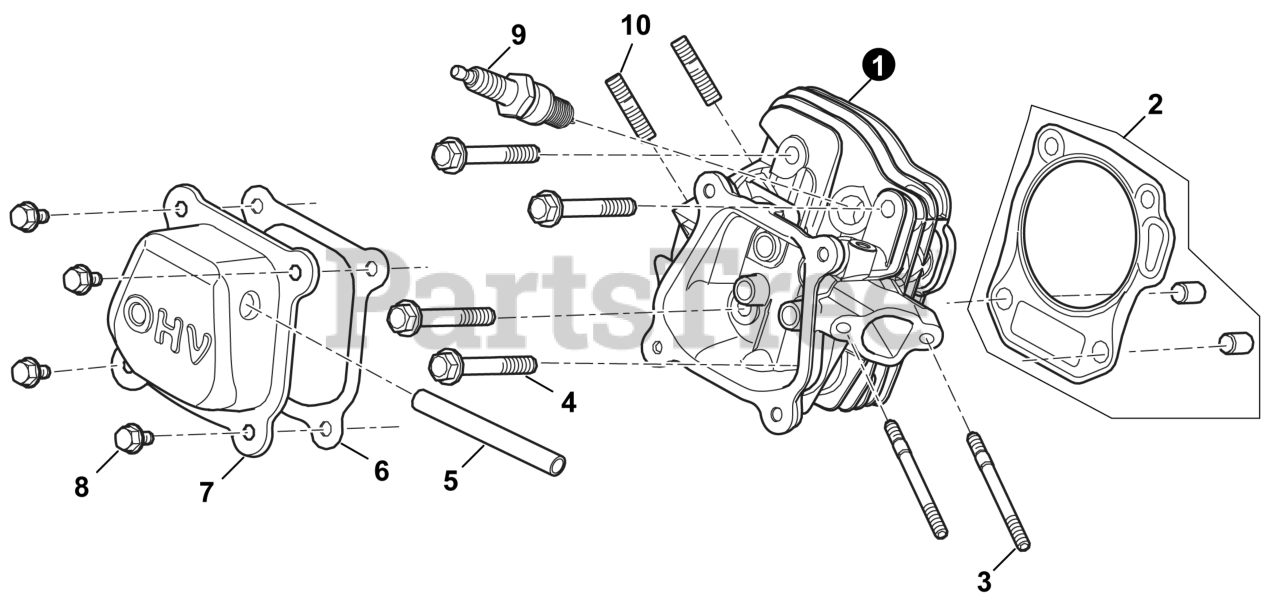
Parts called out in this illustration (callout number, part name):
1	HEAD, CYLINDER
2	GASKET, CYLINDER HEAD
4	BOLT, CYLINDER HEAD
5	TUBE, BREATHER
6	GASKET, VALVE COVER
7	COVER, VALVE
9	SPARK PLUG
